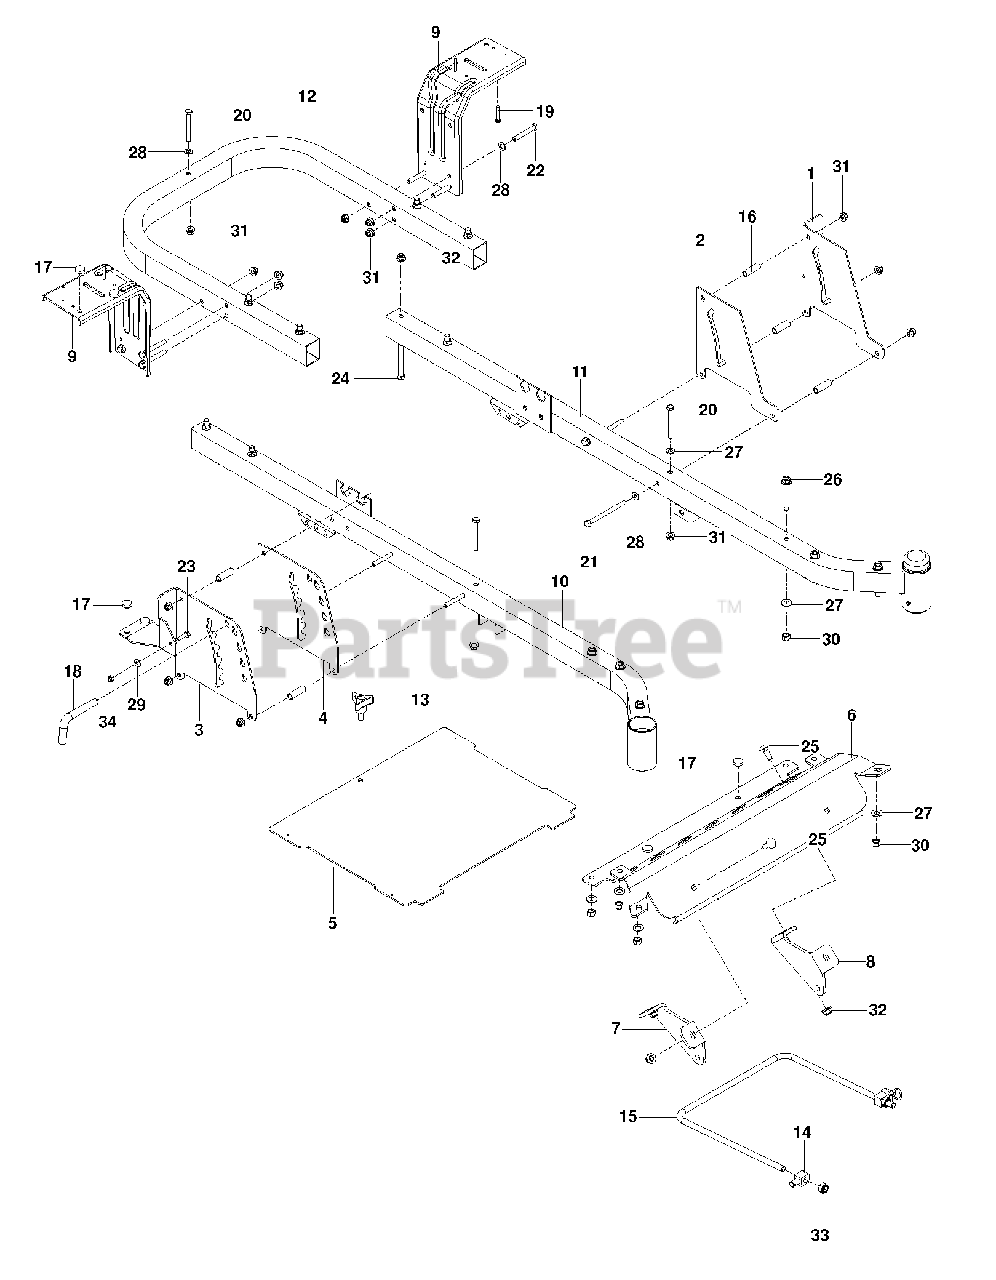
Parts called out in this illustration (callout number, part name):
1	PLATE, OUTER BRAKE, BLACK
2	PLATE, BRAKE LATCH, BLACK
3	PLATE.DECK HEIGHT.PNT.431.RZ
4	PLATE, DECK HEIGHT, BLACK
5	PLATE, FOOT W/DECALS, YLW
6	FOOT, REST, MED YLW
7	MOUNT, STRUT, RT, BLK
8	MOUNT, STRUT, LT, BLK
9	FENDER.SUPPORT.PNT.X431
10	FRAME, FRONT RT, YLW
11	FRAME, FRONT LT, YLW
12	FRAME TUBE, REAR, YLW
13	KNOB W/STUD
14	Swivel Trunion Link Deck Front
15	LINK, FRONT SUSP.
16	Spacer, .334" ID X .5 OD X 1.5
17	GROMMET, BUMPER
18	PIN.DECK.HEIGHT.RZ
19	SCR #10-12X1-1/2HEX WASH HD ZD
20	BOLT HEX
22	CAPSCREW
24	Finished Hex Bolt, 3/8-16 X 3.Gr5
25	RHSNB 3/8C X 1
26	ENGINE BOLT, SPECIAL
27	WASHER 3/8 FLAT
28	WASHER
29	WASHER 1/4 SAE
30	NUT HEX 3/8-16 NYLON, THIN
31	5/16-18 NYLOC FLANGE NUT
32	NUT 3/8-16 HEX FLG NYLOC ZD
33	7/16-14 HEX NUT W/NYL RING ZD
34	LOCKNUT.NYLOC.1/4-20
